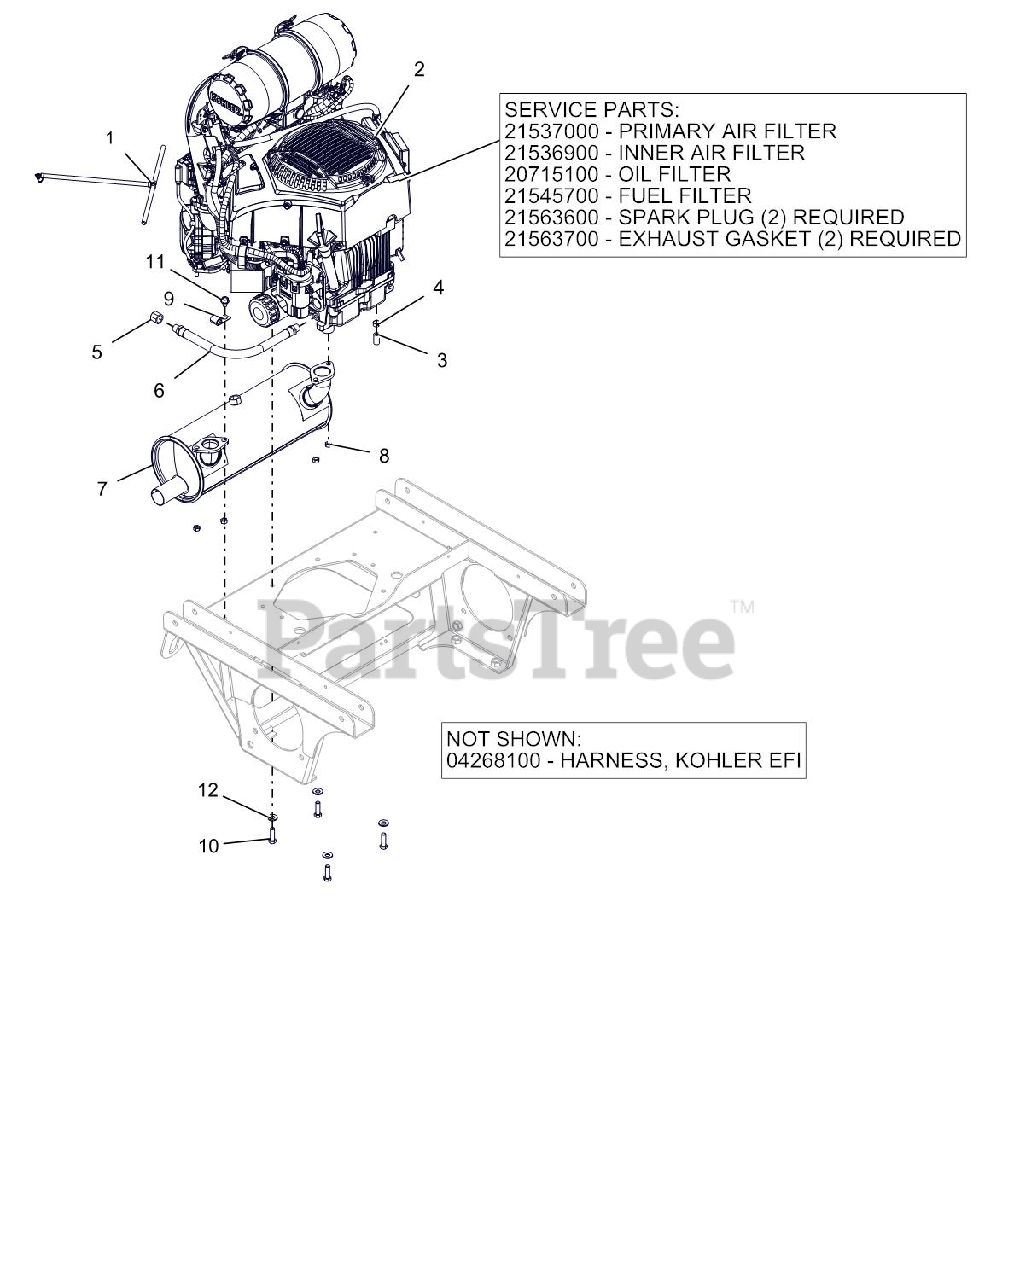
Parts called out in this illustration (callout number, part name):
1	ASM, KOHLER EFI VAPOR LINE
2	ELEMENT, INNER SAFETY
2	ELEMENT, OUTER PRIMARY
2	REGULATOR, EFI FUEL
2	ENGINE, KOHLER EFI
2	FILTER-FUEL KOHLER COURAGE PRO
2	OIL FILTER KOHLER
2	PLUG, SPARK
3	HOSE, .25 LOW-PERM BULK GAS
4	CLAMP, FUEL LINE
5	PIPE CAP 3/8 NPT FEMALE
6	HOSE,HYD .38-14-0K M6N0-M6N0
7	MUFFLER, KOHLER EFI
8	NUT-LK-TOP M8-1.25 YWZC
10	BLT-HEX.38-16X1.25 G5YZ NYTORQ
11	@SCR-TAP .38-16X.50 HWH TR YWZ
12	WASHER, 3/8" SPRING DISC
